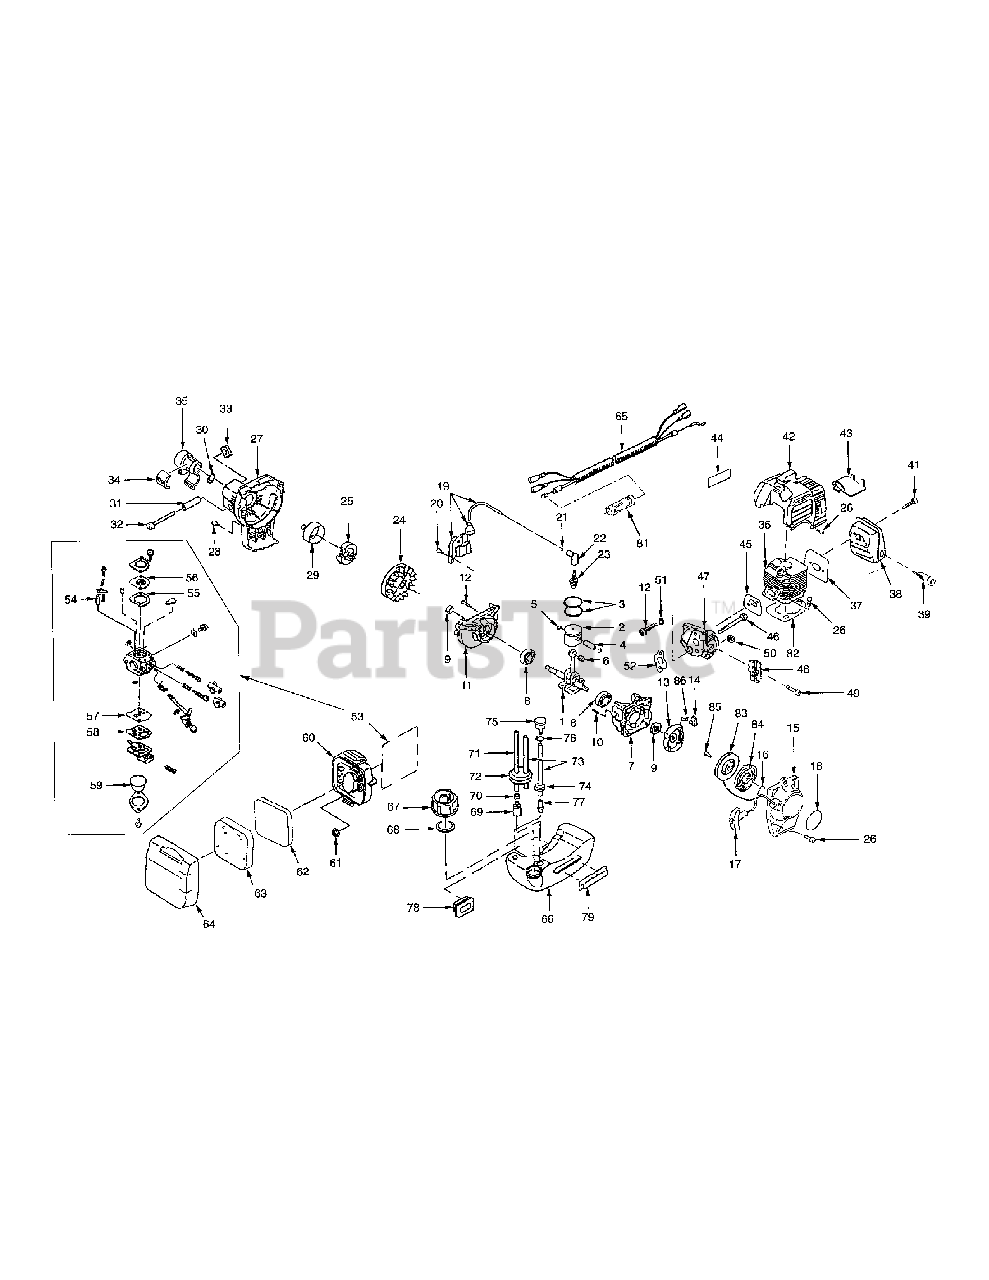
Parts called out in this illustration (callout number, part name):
2	Piston Assembly
3	Ring, Piston
5	Clip, Piston Pin
6	Bearing, Needle
7	Crankcase Assembly
8	Bearing, Ball, 6201
11	Crankcase Assembly
12	Bolt, M5x25 .
13	Pulley Assembly, Starter
15	Recoil Assembly
16	Rope, Starter
17	Knob, Starter
19	Coil Assembly, Ignition
20	Bolt, M4x20 .
23	Spark Plug
24	Flywheel, Magneto
25	Clutch Assembly
26	Bolt, M5x20 .
27	Housing, Blower
28	Bolt, M5x16 .
29	Drum, Clutch
30	Snap Ring, S-12
32	Bolt, M5x30 .
37	Gasket, Muffler
41	Bolt, M5x48 .
42	Cowling, Cylinder
43	Baffle Plate
45	Gasket, Insulator
46	Bolt, M5x56 .
49	Bolt, M5x12 .
51	Washer
52	Gasket
53	Carburetor Assembly
54	Valve, Float
56	Diaphragm, Metering
57	Diaphragm, Pump
60	Case, Air Silencer
62	Element "B", Air Filter
63	Element "A", Air Filter
65	Wire Complete;,Throttle
67	Cap Assembly, Fuel Tank
69	Filter, Fuel
71	Hose
73	Hose
75	Valve, Reversing
79	Rubber
82	Gasket, Cylinder
84	Spring, Spiral
86	Spring, Return
